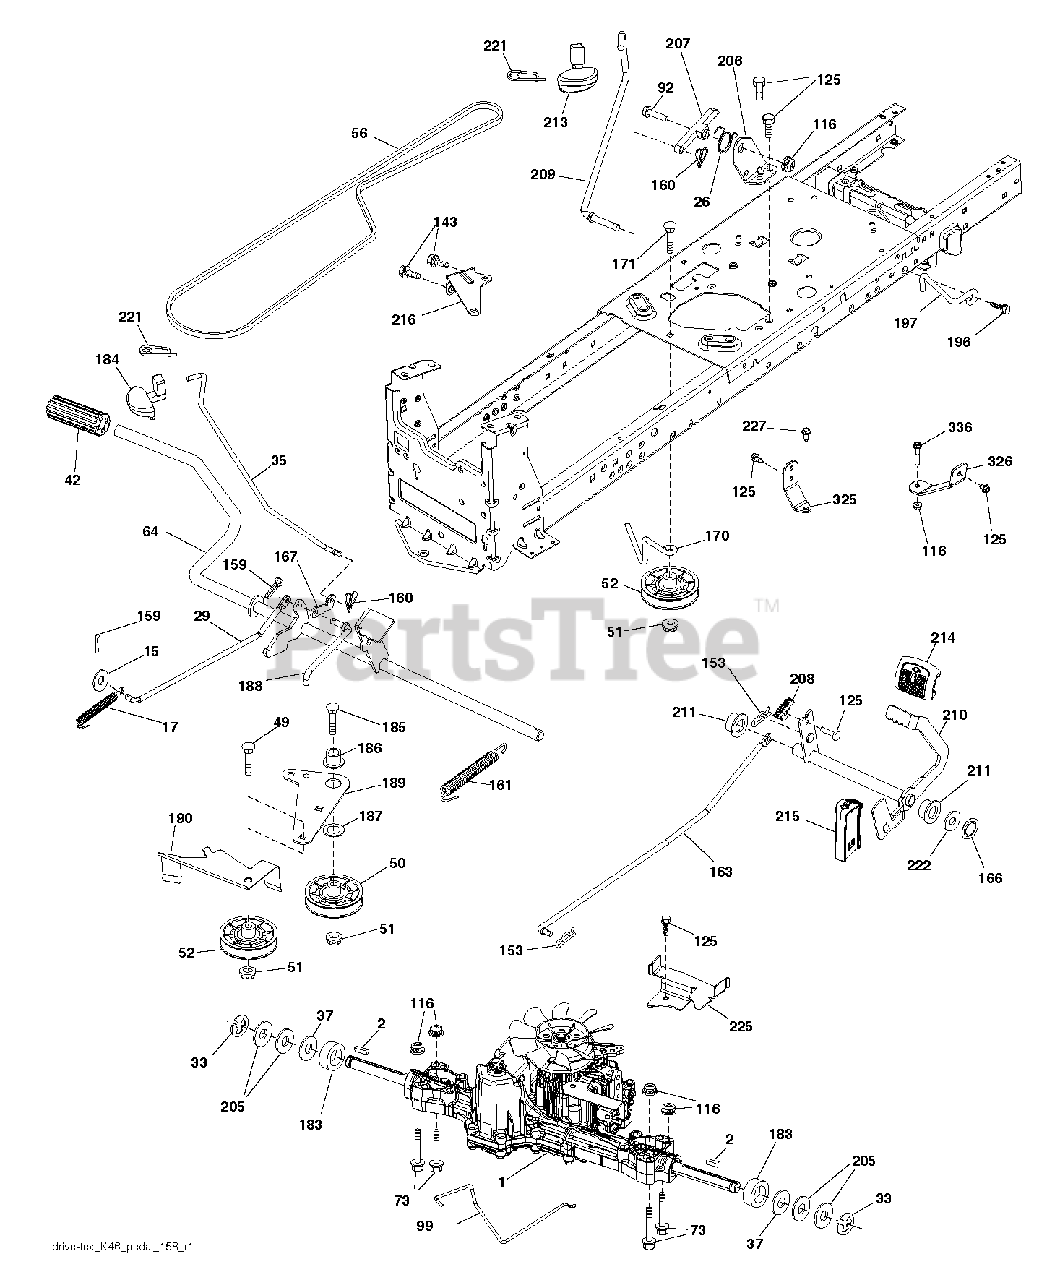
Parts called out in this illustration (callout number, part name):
2	SQUARE KEY
15	WASHER
17	SPRING.BRAKE.K46.GREEN
26	SPRING.RETURN.CRUISE
29	ROD.BRAKE.K46
35	ROD .BRAKE. PARKING. GT. HUSQ.
37	WASHER.HARDENED
42	PEDAL COVER T
50	IDLER.FLAT.910.OFFSET
51	NUT LOCK FLG 3/8-16 UNC
52	IDLER.V-GROOVE.910.OFFSET
56	V-BELT.MOWER.92.40.42/K46
64	SHAFT.ASM.PEDAL.BRK.CNTR
92	BOLT
99	ROD.SPRING.BYPASS.K46.LT.Z
116	NUT LOCK HEX FLANGE 5/16-18
125	SCREW
143	SCREW LT
153	RETAINER M
159	COTTER PIN
160	RETAINER CLIP
161	SPRING, RETURN LT
163	ROD.CONTROL.K57R.K46
166	NUT.PUSH.625
167	LATCH.BRAKE.SPRING
170	KEEPER.V-IDLER.CENTER.
183	SPACER AXLE
184	HANDLE.PARKING.BRAKE.H (BLK)
186	SPACER.RETAINER
187	WASHER 12/32X2X10GA
188	RP LINK.CLUTCH.GROUND.DRIVE
189	BELLCRANK.GROUND.DRIVE.TEX.
190	KEEPER.BELLCRANK.DRIVE
196	SCREW 3/8-16X1
197	CLUTCH.ANTIROTATION.WIREFORM.
206	BRACKET.MOUNT.CRUISE.LATCH
207	LATCH.CONTROL.CRUISE.TEX
208	GEAR.SECTOR.CONTROL.CR
209	ROD.CONTROL.CRUISE.GT.
210	ROCKER.ASM.PEDAL.CONTR
211	BEARING.NYLON
213	KNOB.CONTROL.CRUSIE.HU
214	PEDAL.FORWARD.PAD.TEX
215	PEDAL.REVERSE.TEX.GT.4
216	BRACKET.PULLEY.IDLER.W/TEX
221	RETAINER.SPRING.CLIP.H
222	WASHER 21/32 X 1-1/4 X 10 GA.
225	KEEPER.BELT.TRANSAXLE.K46
227	SCREW
325	BRACKET.TRQ.STP.46.20".TIRE.LH
326	BRCKT.PNT.TRQ.STP.46.20TIRE.RH
336	BOLT.5/16-18X1-3/4.FLANGED.HEX
